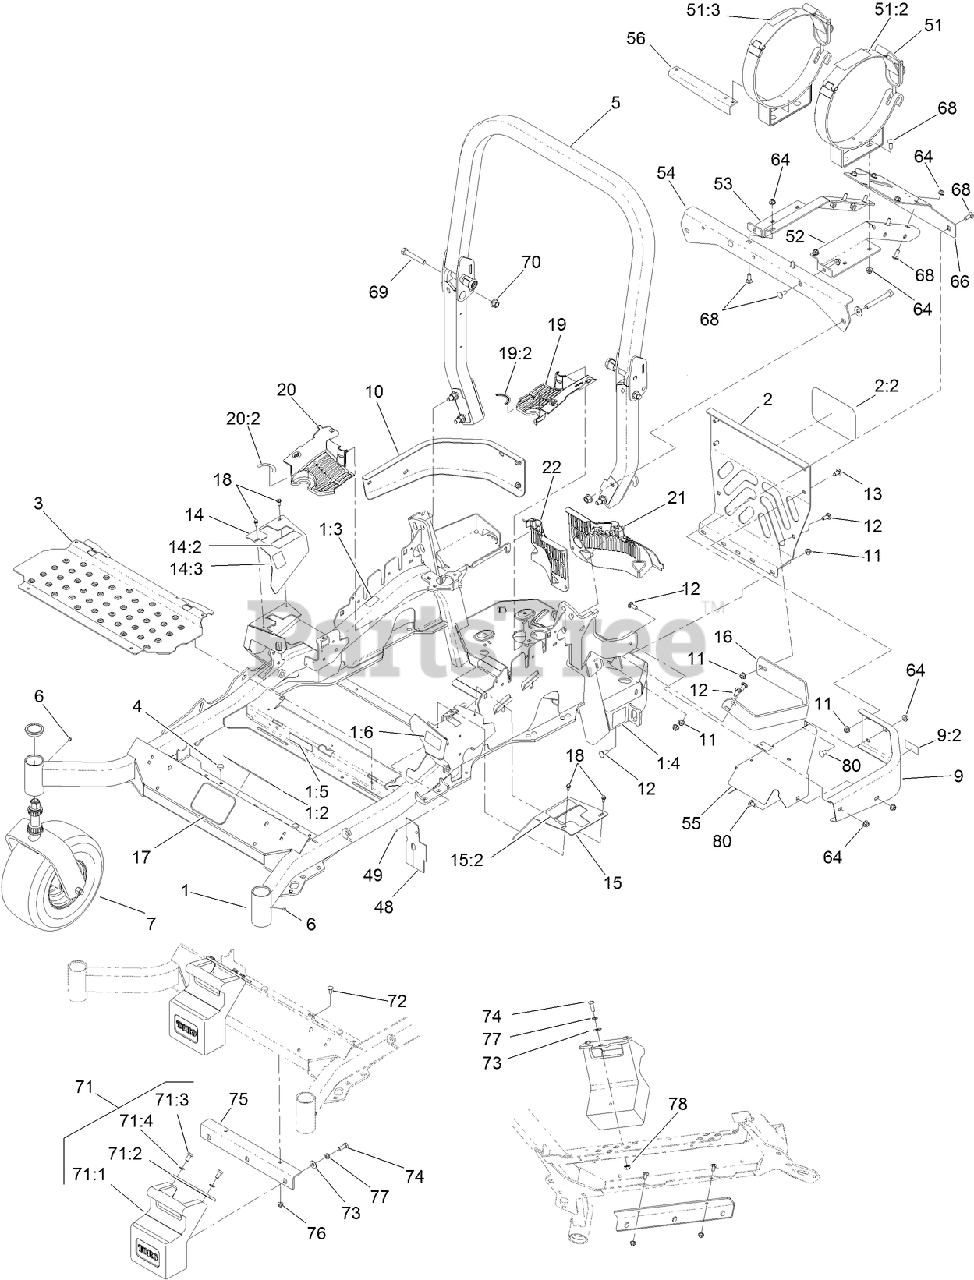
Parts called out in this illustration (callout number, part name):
1	MAIN FRAME ASM
1:2	DECAL-CAUTION
1:3	DECAL-SLOPE
1:4	DECAL-BELT DRIVE
1:5	DECAL-SPARK ARRESTER
1:6	DECAL-FUEL FILL
2	REAR GUARD ASM
2:2	DECAL
3	FLOORPAN
4	BUMPER
5	ROPS ASM
7	Caster Wheel ASM
9	LH BUMPER ASM
9:2	DECAL-CAUTION
10	BUMPER-RH
11	NUT-HF, NI
12	SCREW-CARR
13	SCREW-CARR
14	RH MOTION CONTROL COVER ASM
14:2	DECAL-MOTION CONTROL
14:3	DECAL-PARK BRAKE
15	LH MOTION CONTROL COVER ASM
15:2	DECAL-MOTION CONTROL
16	GUARD-MUFFLER
17	DECAL
18	SCREW-HWH
19	LH HYDRO GUARD ASM
19:2	DECAL-HYDRO OIL
20	RH HYDRO GUARD ASM
20:2	DECAL-HYDRO OIL
21	GUARD-HYDRO, REAR (LH)
22	GUARD-HYDRO, REAR (RH)
48	DEFLECTOR-AIR FLOW
49	RIVET-POP
51	TANK BRACKET ASM (SET)
51:2	DECAL-LPG WARNING
51:3	DECAL-LPG 43.5LB TANK
52	LH LPG FRAME ASM
53	RH LPG FRAME ASM
54	SUPPORT-LPG FRAME, FRONT
55	PANEL-LPG, AC
56	PLATE-INDEX, LPG TANK
64	NUT-HF, NI
66	SUPPORT-REAR FRAME, LPG
68	BOLT-CARR
69	SCREW-HH
70	NUT-LOCK
71	WEIGHT ASM
71:1	WEIGHT-43 LB
71:2	TAB-SUPPORT, WEIGHT
71:3	SCREW-HH
71:4	WASHER-LOCK
72	SCREW-CARR
73	WASHER-FLAT
74	SCREW-HH
75	BRACKET-MOUNT, WEIGHT
76	NUT-HF, NI
77	WASHER-LOCK
78	NUT-HF, NI
80	SCREW-CARR
